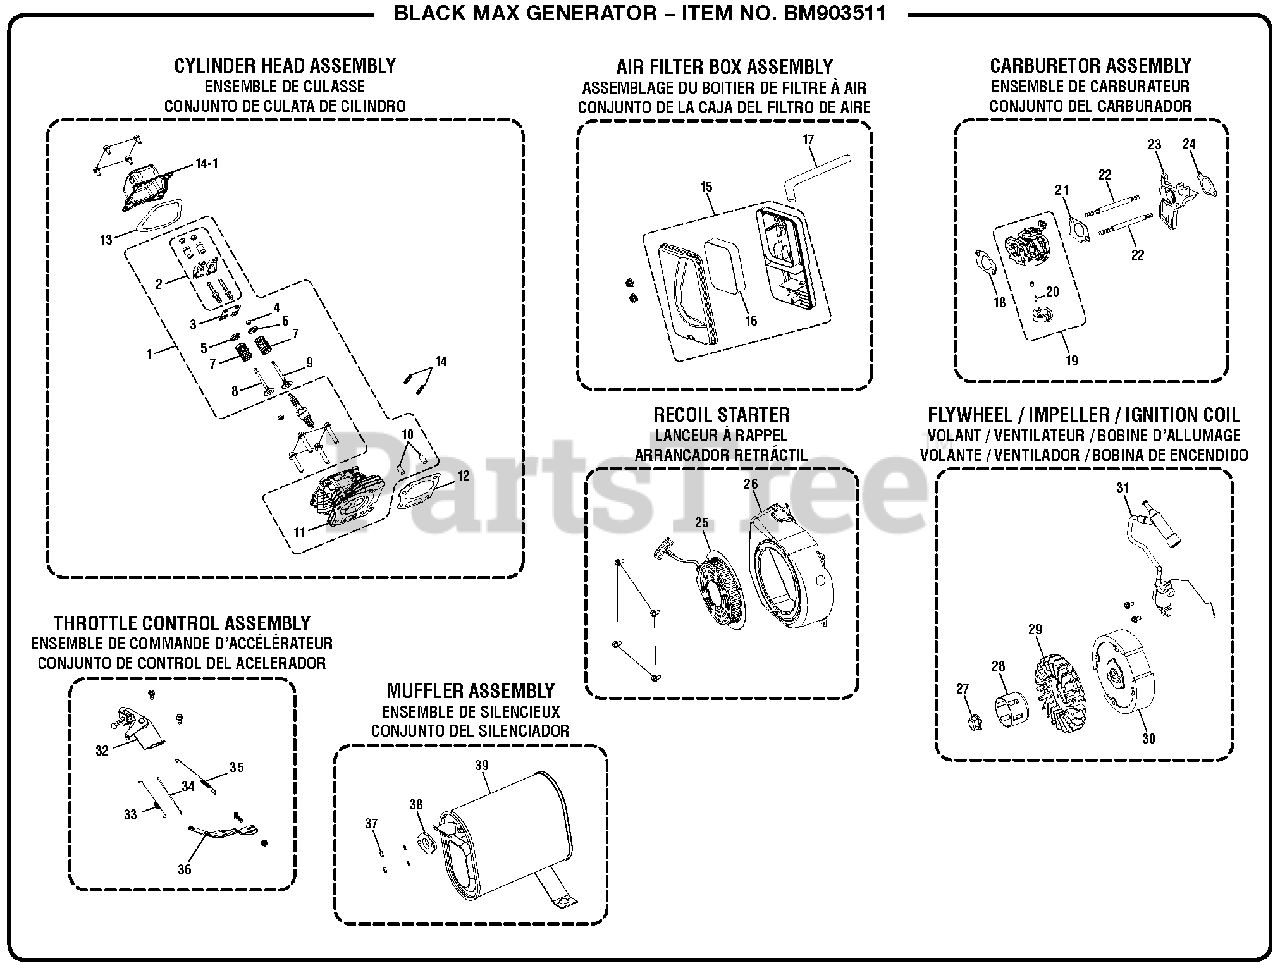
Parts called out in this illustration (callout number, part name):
1	Cylinder Head Assembly
2	Rocker Assembly
3	Guide Plate
4	Rotator
5	Valve Spring Seat (Intake)
6	Valve Spring Seat (Exhaust)
7	Valve Spring
8	Intake Valve
9	Valve Exhaust
10	Dowel Pin
11	Cylinder Head
12	Cylinder Head Gasket
13	Cylinder Head Cover Gasket
14	Threaded Stud
14-1	Valve Cover
15	Air Cleaner Assembly
16	Air Filter
18	Spacer
19	Carburetor Assembly
20	Needle Valve
21	Carburetor Gasket
22	Threaded Stud
23	Carburetor Insulator
24	Intake Gasket
25	Recoil Starter
26	Recoil Starter Cover
27	Nut
28	Starter Pulley
29	Recoil Starter Fan
30	Flywheel Assembly
31	Ignition Coil Assembly
32	Throttle Assembly
33	Governor Spring
34	Governor Rod
35	Throttle Return Spring
36	Governor Arm
37	Hex Nut
38	Exhaust Gasket
39	Muffler Assembly
